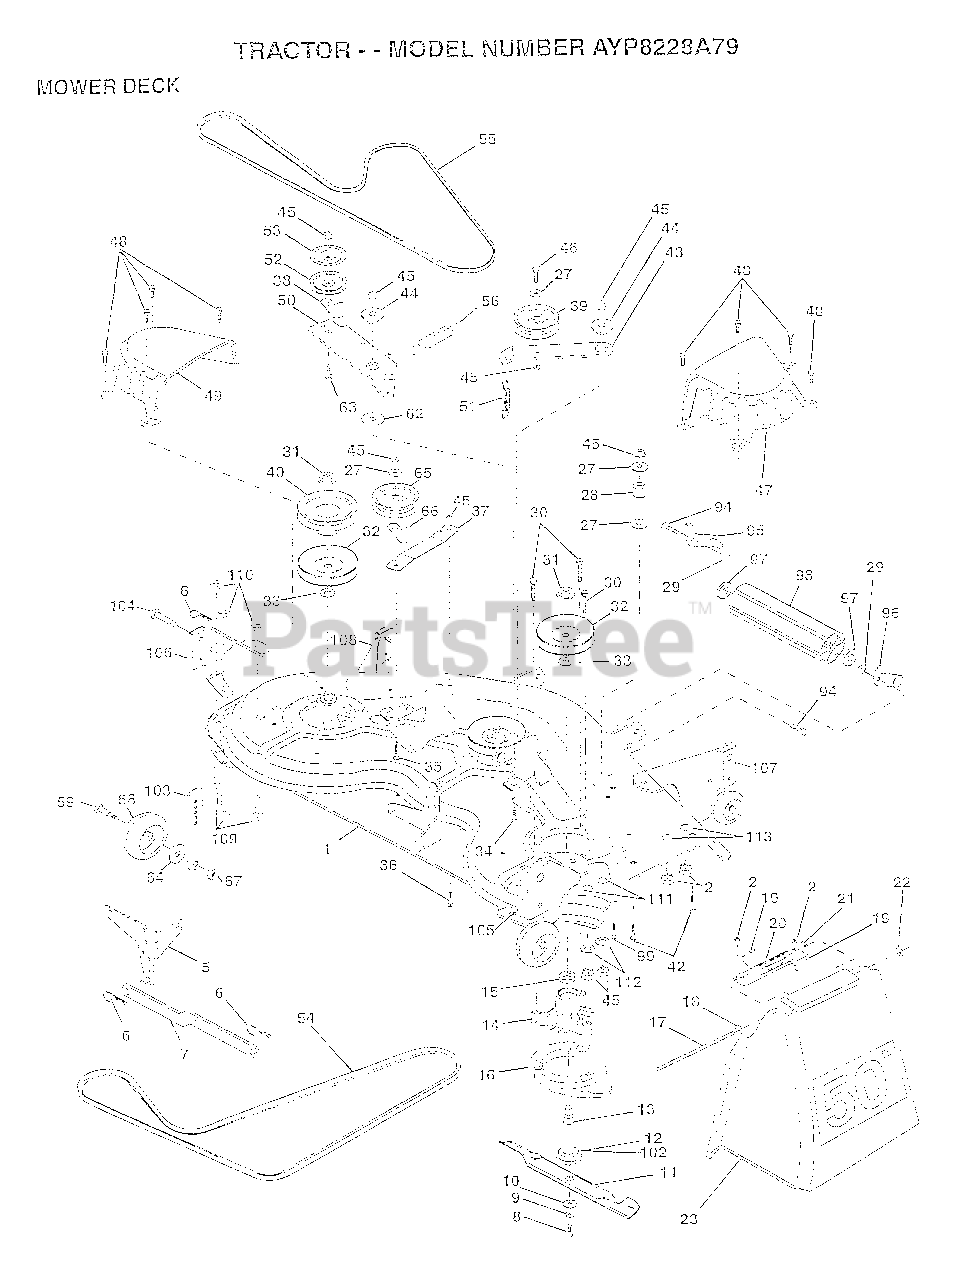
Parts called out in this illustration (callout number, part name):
1	"DECK ASM-50"""
4	RUNNER-LH M
5	BRKT.ASM.SW.44/50
8	BLADE BOLT
10	WASHER.HARD.BLADE
11	"BLADE.50"" HD"
12	BEARING.BALL
13	SHAFT.ASM.W/BRNG
14	HOUSING.MAND.44.V
15	BEARING
16	STRIPPER RND MWR
17	ROD-HINGE T
18	WASHER
19	CAP-SLEEVE LT
20	SPRING TORSION
21	BRKT DEFLECTOR
23	DEFLECTOR
24	"RUNNER RH 50"" DK"
25	WASHER M
27	WASHER
29	NUT
32	PULLEY.MANDREL.42
33	WASHER
34	BOLT.3/8-14X1.25
35	BOLT
36	BOLT D
37	STIFFENER.ARM.IDL
38	"KEEPER-BELT,IDLER"
39	FLAT IDLER PULLEY
40	"PULLEY.DRIVEN.44"""
42	BOLT
43	"ARM.IDLER.SEC.44"""
44	SPACER RETAINER
47	"COVER.MAND.RH.44"""
48	SCREW.1/4-20X5/8
49	COVER.MANDREL.LH
50	ARM.IDLER.PRIMARY
51	"SPRING.SEC.44""VEN"
52	PULLEY.IDLER.VGRO
53	SHIELD.IDLER.44.V
54	BELT V PRIM 50
55	BELT-V.SEC.46.KEL
56	SPRING.EXT.DECK.
57	BAR.ASM.GUAGE.WHL
58	WHEEL GAGE DONUT
59	BOLT.SHOULDER
60	PIN.CLEVIS
61	BRACKET.GUAGE.WHL
62	HARDENED WASHER
63	BOLT.3/8-16X1.50
64	WASHER
65	PULLEY IDELR FLAT
66	"KEEPER-BELT,IDLER"
67	LOCKNUT
94	BOLT
97	WASHER
99	BOLT
102	WASHER.FELT.
